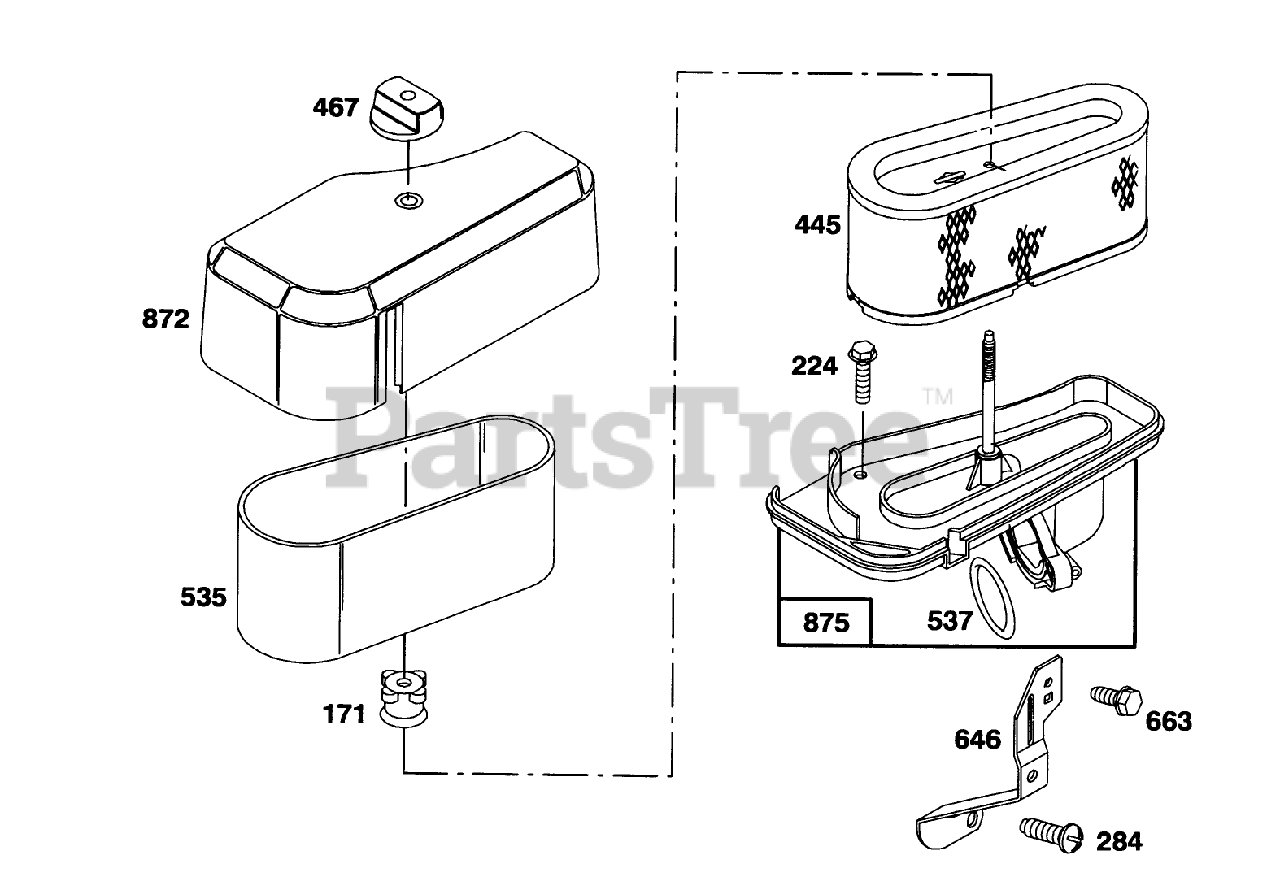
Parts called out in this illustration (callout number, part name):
224	Screw-Sem
284	Screw-Pan Head
445	Filter-Air
535	Filter-Air
537	O-Ring
646	Brace-Air Cleaner
663	Screw
872	Cover-Air Cleaner
875	Base-Air Cleaner
